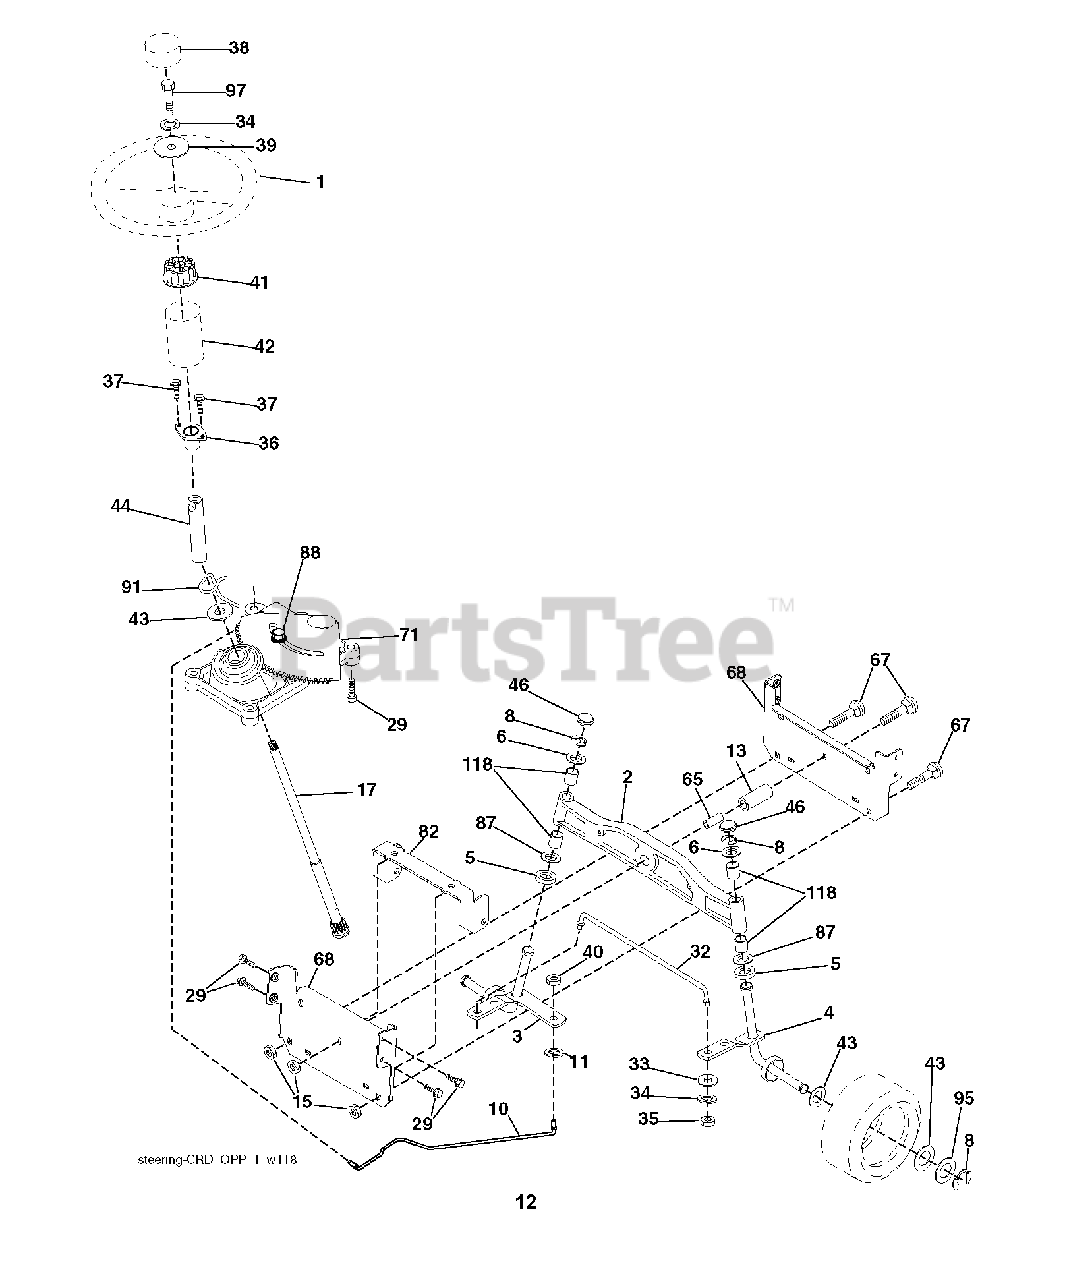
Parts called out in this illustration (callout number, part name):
1	WHEEL.STEERING.STDSRR.BLK/OV
2	AXLE.ASM.LT.CAST.LGHTWGHT
3	SPINDLE.ASM.LH.15"TIRES
4	SPINDLE.ASM.RH.15"TIRES
8	RING CLIP
10	DRAGLINK.15".TIRES.2001
11	WASHER, LOCK 3/8
13	TUBE, PIVOT AXLE
15	NUT
17	SHAFT STEERING SPLINE
29	SCREW, 3/8-16X3/4
32	ROD.ASM.TIE.BALL.JOINT.NOVAN
33	WASHER M
34	LOCKWASHER
35	NUT, CROWNLOCK
36	BUSHING, STEERING
38	CAP.WHL.STRNG.STDSRRD.SRS.BLK
39	WASHER.11/32
40	NUT CROWNLOCK 3/8-24
41	ADAPTER, WHEEL STNG..
42	BOOT.STEERING.SHAFT.BLACK
44	SHAFT.EXTEN.STRG.SPLINE
46	CAP.SPINDLE
65	SPACER.BRACE.AXLE
67	BOLT CARRIAGE
68	BRACE.AXLE.15"TIRES
71	STEERING ASM
82	BRACKET.SUSP.CHASSIS.FRONT.15
87	WASHER, FLAT .781 X 1 1/2"
88	BOLT, SHOULDER 7/16-20
91	CLIP.STEERING
95	WASHER.HARDENED
118	BUSHING, AXLE CAST
